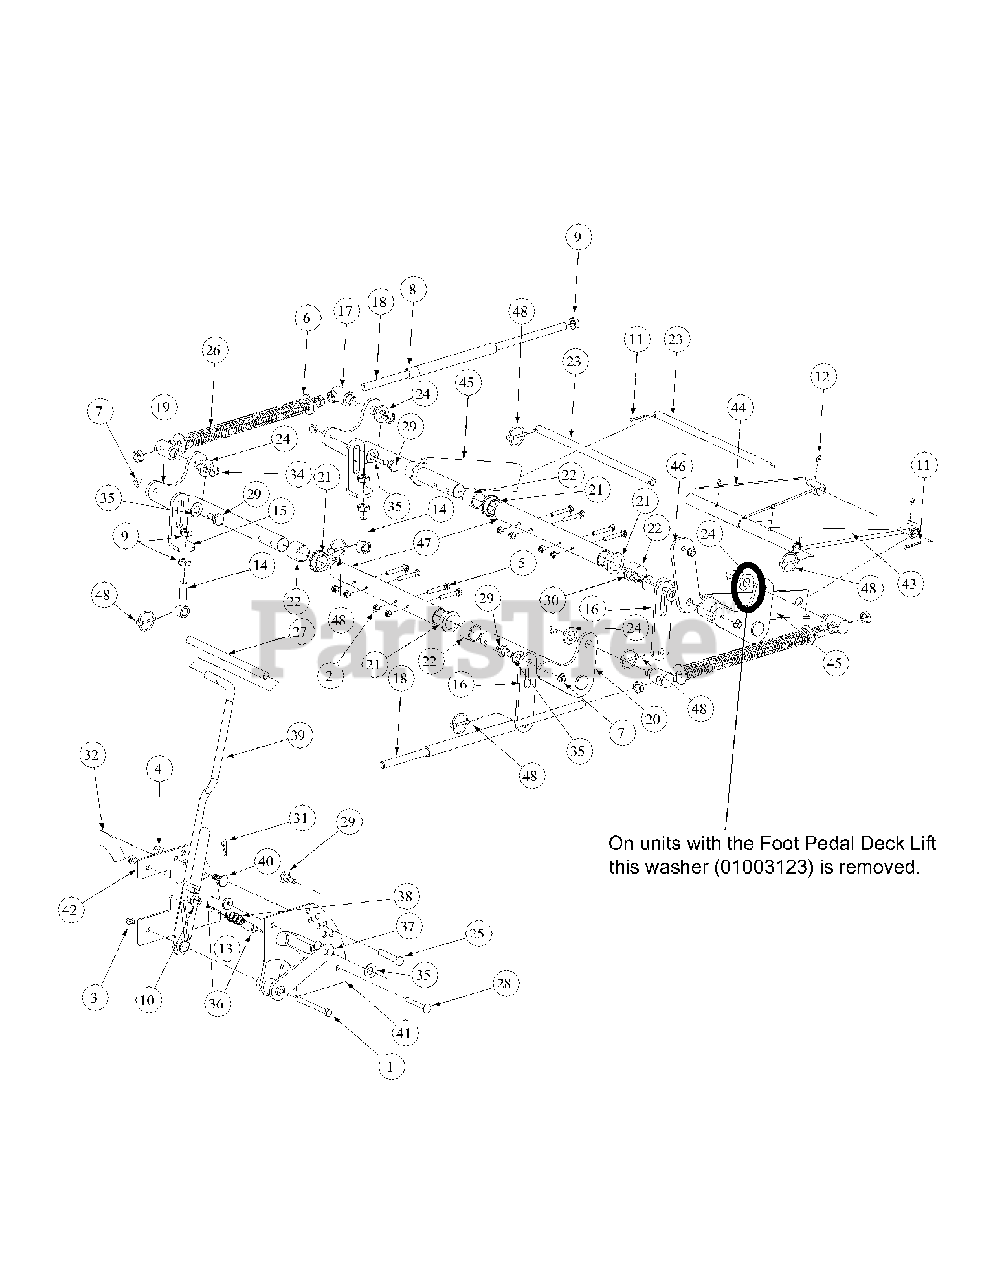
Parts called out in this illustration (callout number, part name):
1	Hex Cap Screw, 3/8-16, 3.75
2	Nut, 5/16-18, Nylock
3	Nylock Insert Lock Nut, 3/8-16
4	Nylock Insert Lock Nut, 1/2-13
5	Hex Cap Screw, 5/16-18 x 2
6	Flat Washer, 5/8
7	Hex Nut, Flange Lock, 3/8-16
8	PVC Hose, 5/8 ID x 13/16 OD x 8"
9	Jam Nut, 5/8-11
10	Flat Washer, .06, .776, 1.25
11	Cotter Pin, 3/16 x 1-1
12	Grease Fitting, 1/4-28 x 3/16
13	Idler Washer
14	Eye Bolt, 5/8ID
15	Eye Bolt Mount Link, 5/8 ID
16	Deck Link
17	Ferule Lift
18	Lift Connector Rod
19	Bellecrank Weldment Lift, Left Hand
20	Bellecrank Weldment Lift, Right Hand
21	Hex Flange Bearing, 1.25 ID
22	Frame Lift Spacer
23	Front Lift Link, Rod Mount
24	Spacer, .812 ID x .268 Lg.
25	Clevis Pin, .500 Dia. x 2.625 Lg.
26	Lift Compression Spring
27	Lift Handle Grip
28	Carriage Bolt, 3/8-16, 2.75
29	Shoulder Screw, 0.625 OD x .437 Lg.
30	Shoulder Screw, 0.625 OD x .830 Lg.
31	Cotter Pin, .148 x 3.00
32	Decal Height Indicator
34	E Clip, 3/4 Dia.
35	Nylon Flat Washer, 5/8
36	Spacer, .39 ID x .63 OD x 1.442
37	Lift Pivot Assembly
38	Lift Handle Spring
39	Lift Handle Assembly
40	Shoulder Screw, 5/8 OD x 0.264
41	Outer Lift Index Plate
42	Inner Lift Index Plate
43	Bearing Lift Brace Assembly, Right Hand
44	Bearing Lift Brace Assembly, Left Hand
45	Front Frame Strut Assembly
46	Lift Link Adjustment
47	Lift Shaft Holder
48	Linch Pin, 3/16
